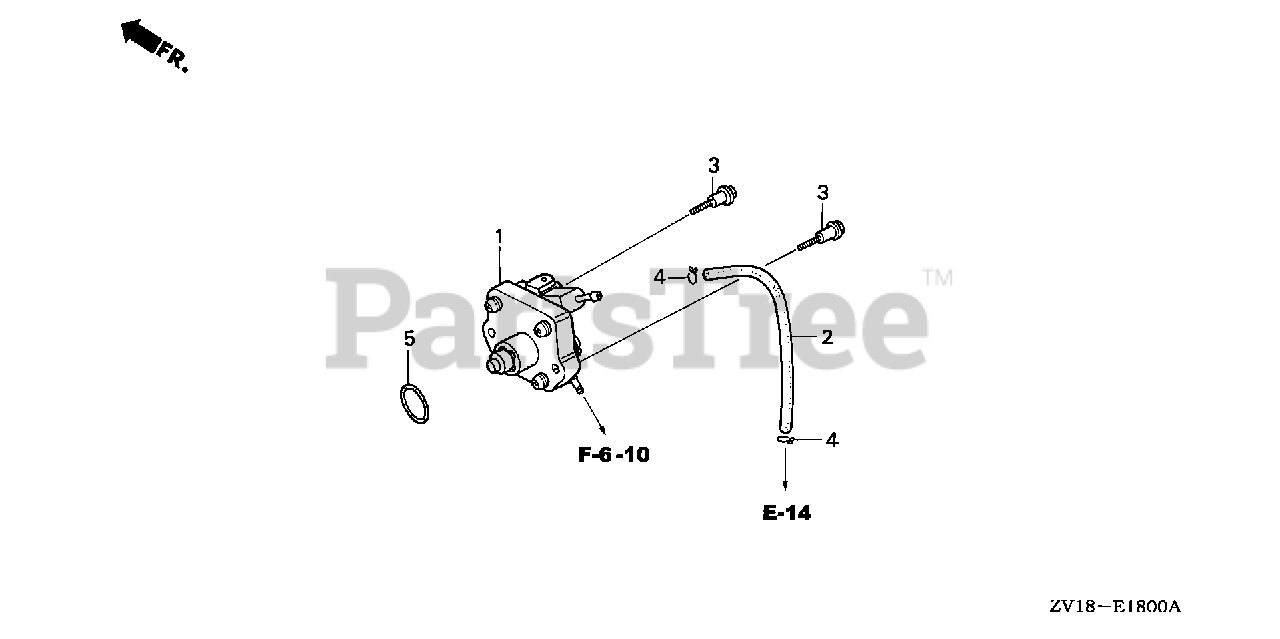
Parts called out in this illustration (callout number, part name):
1	PUMP ASSY., FUEL
1	PUMP ASSY., FUEL (MSDS)
2	TUBE, FUEL (4.5)
2	TUBE C, FUEL
3	BOLT, SPECIAL (6X34)
4	CLIP, TUBE (B8)
5	O-RING (20.8X2.4)
